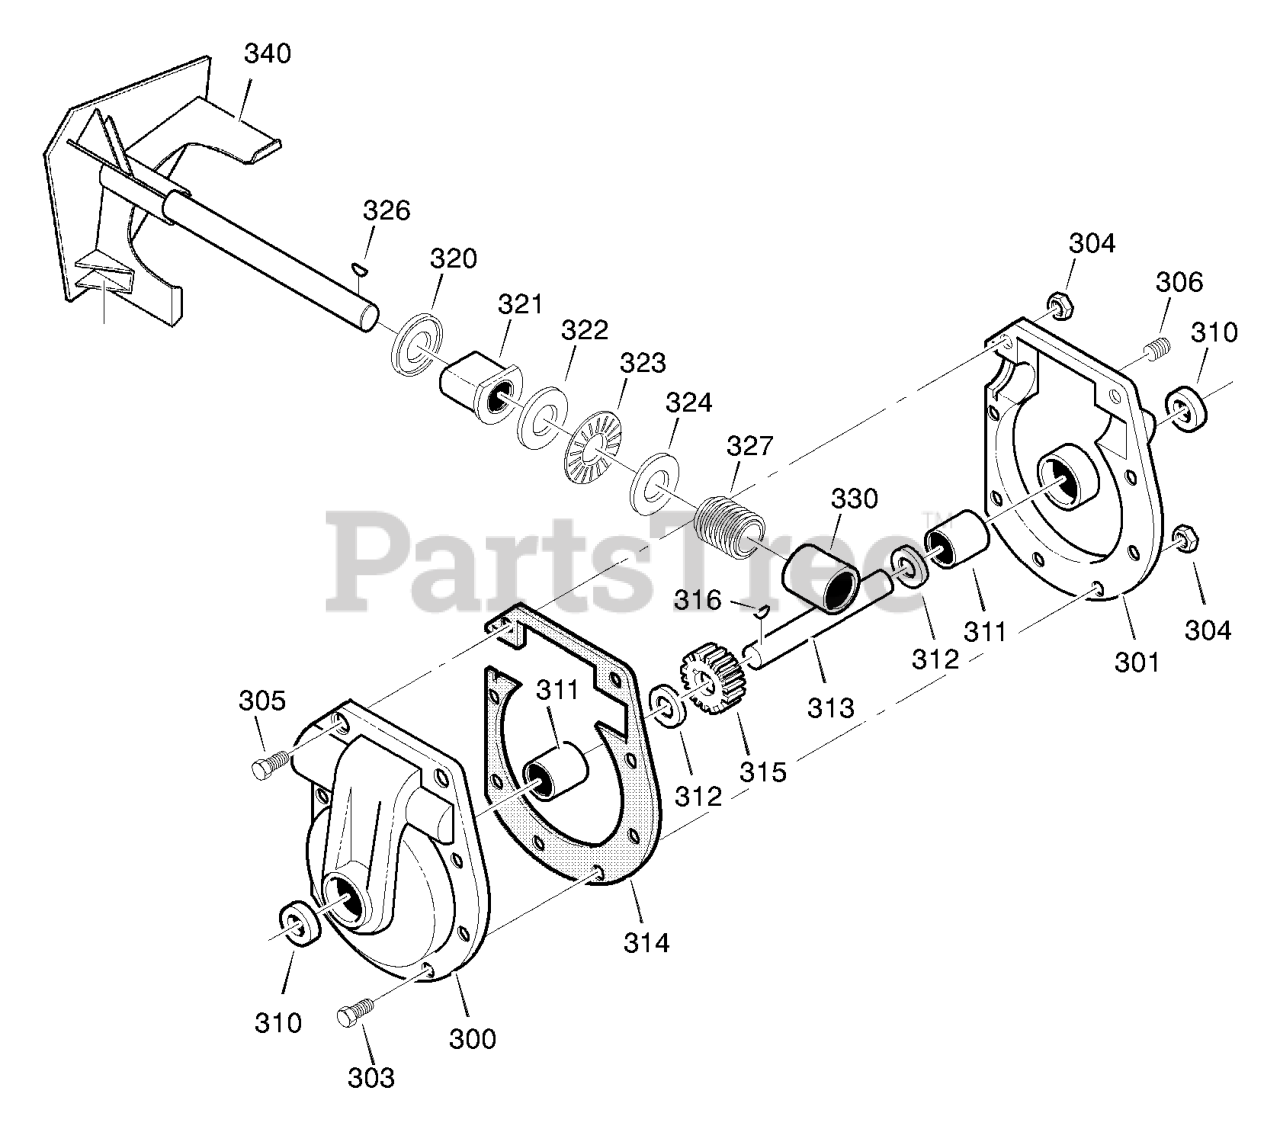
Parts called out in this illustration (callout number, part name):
300	CASE, GEAR, RH
301	CASE, GEAR, LH
303	SCREW,1/4-20X.75
304	NUT,1/4-20
305	NUT, 1/4-20 HEXKEPS
306	SCREW, 3/8-16 x 0.50
310	SEAL, OIL
311	BEARING, FL
312	WASHER, FLAT
313	SHAFT, AUGER OUTPUT
314	GASKET, GEAR BOX
315	WORM GEAR
316	KEY, WOODRUFF #61
320	BRNG, FL
321	SHAFT, AUGER INPUT
322	COLLAR, THRUST
323	PIN, SPRING
324	WASHER, FLAT
326	BRNG, FL
327	SEAL, OIL
330	BEARING
340	IMPELLER
